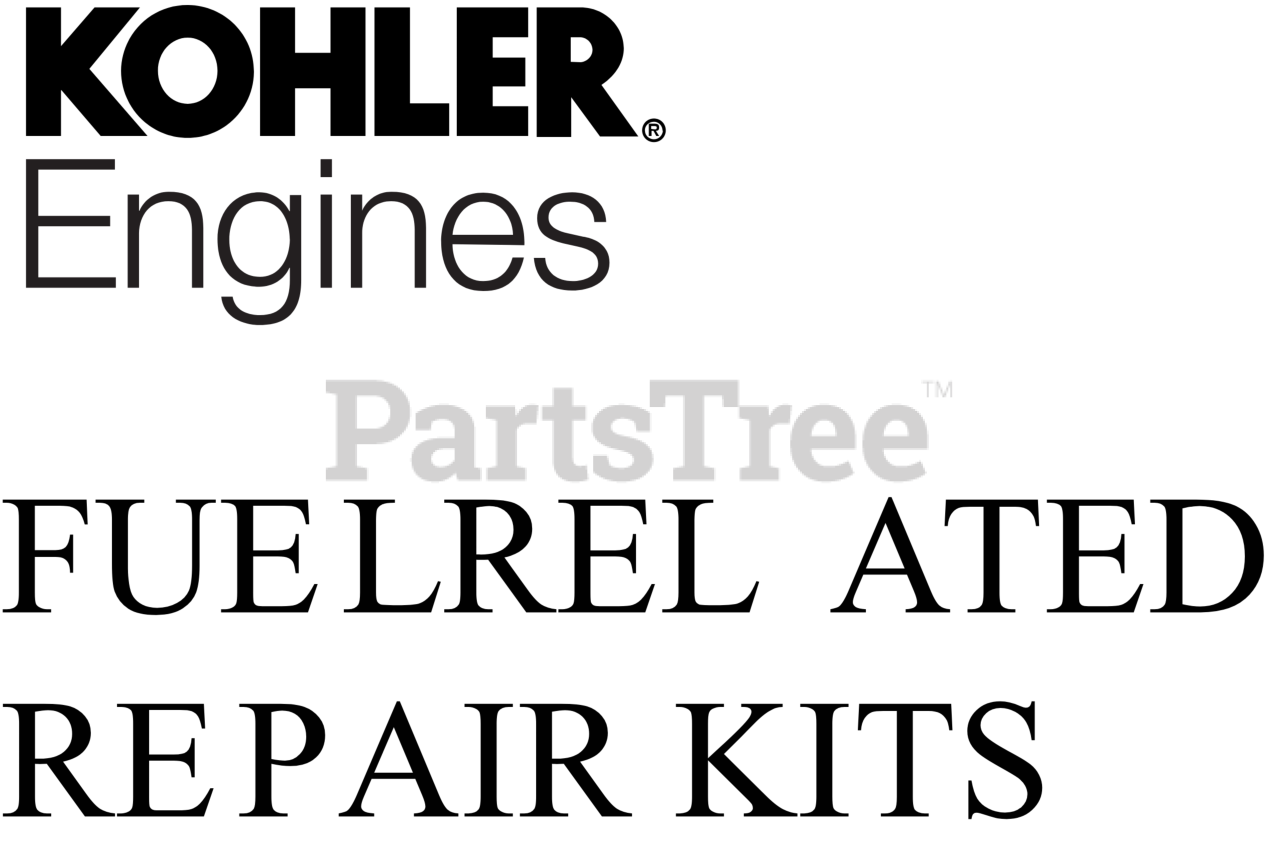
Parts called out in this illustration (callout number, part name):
NI	KIT, CARBURETOR REPAIR (HUAYI)
NI	KIT, HIGH ALTITUDE 4000-8000'
NI	KIT, HIGH ALTITUDE ABOVE 8000'
